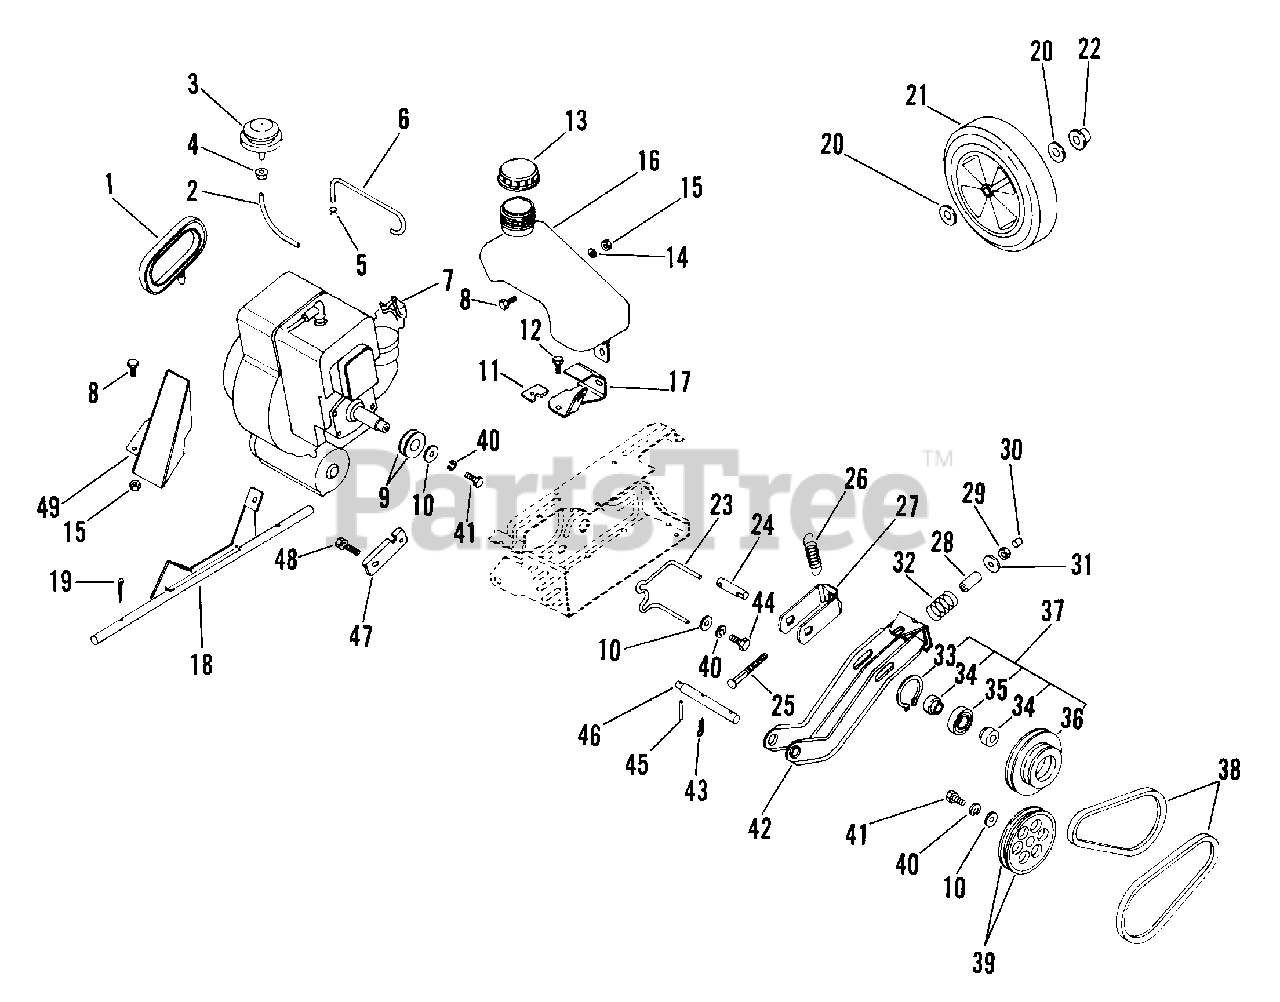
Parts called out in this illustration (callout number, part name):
1	HANDLE, RECOIL START
2	PRIMER LINE
3	PRIMER ASSY
4	NUT-LK-FLG .250-20 PL
5	CLAMP-HOSE WIR.490/.510X.092#8
6	FUEL LINE
7	ENGINE - 3 HP
8	BLT-HEX .25-20X.50 PL GR2
9	SHEAVE HALF - ENGINE
10	WSHR-FL-STL .328X.875X.062 PL
12	SCR-TAP .312-18X.50 HWH PL TR
13	FUEL CAP 2 CYCLE ORANGE
14	WSHR-FL-STL.312X.734X.065PL
15	NUT-LK-CTR .250-20 PL
16	FUEL TANK
17	TANK BRACKET
18	AXLE WELDMENT
19	PIN-COTR .09X.75 PL
20	WSHR-FL-STL .531X.938X.104 PL
21	T/WHL ASSY
22	PUSH CAP
23	BELT FINGER
25	BLT-RDHDSQNK .31-18X3.25 SHTPL
26	SG-TENS .080X.80X2.48 WLD 6
27	TENSION BRACKET
28	SPACER .400X.530X1.120
29	NUT-LK-NYL.312-18 PL
30	CAP, VINYL, .25 ID
31	WSHR-FL-STL .328X1.0X.094 PL
32	SG-COMP .148X.87X1.50
33	RG-RTNG-INT 1.620X.062
34	BSHG-FLG .504X.670X.640X.900
35	BRG-BALL .669X1.575X.47 (6203)
36	SHEAVE-ALUM
37	PULLEY ASSEMBLY
38	BELT SET
39	SHEAVE HALF - IMPELLER
40	WSHR-LK .313X.078 PL MED
41	BLT-HEX .31-24X.50 GR5
42	BRACKET - PIVOT
43	PIN-HAIR INT .09X.188 PL
44	BLT-HEX .31-18X.75 PL GR2
45	PIN-ROLL .125X1.00
47	PLATE-PIN
48	BLT-SERHFWH .25-20X.50 PL
49	EXHAUST DEFLECTOR W/DECAL
